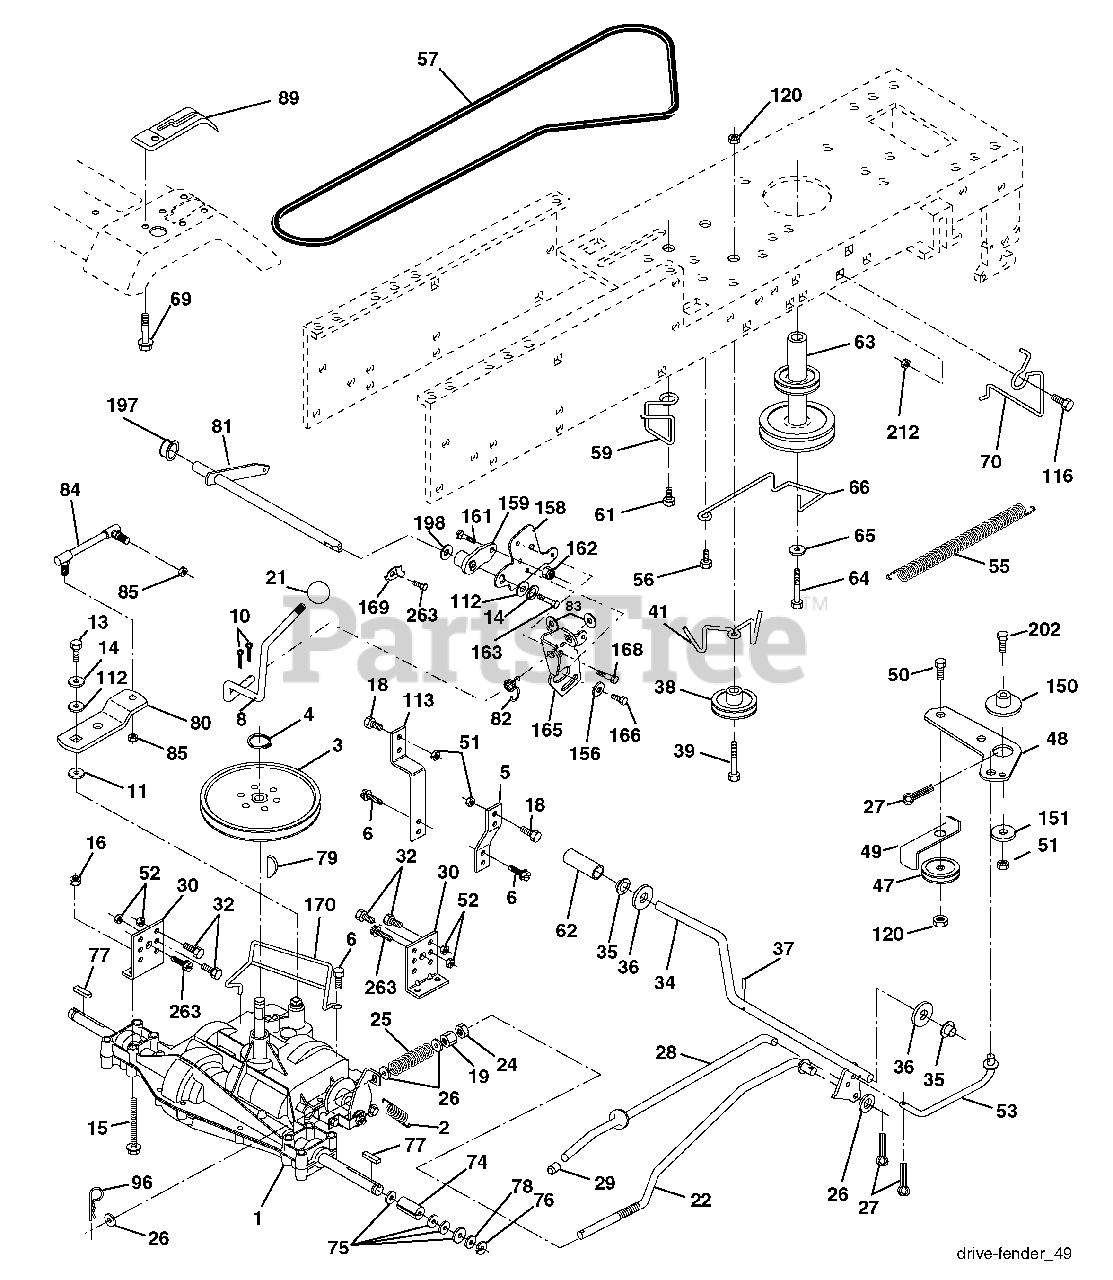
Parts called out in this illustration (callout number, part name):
2	Spring Return Brake
3	Pulley Transaxle 18"tires
4	Ring Retainer # 5100-62
5	Strap Torque 30 Degrees RH
6	Screw 5/16-18 x 3/4
8	Rod Shifter Blk
10	Pin Cotter 1/8 x 1 Cad
11	Washer Plate Shf 388 Sq Hole
13	Bolt 1/4-28 unf Gr. 8 w/Patch
14	Washer Lock Hvy Helical 1/4
15	Bolt Hex Flghd 5/16-18 Gr. 5
16	Nut 5/16-18
18	Bolt Fin Hex 3/8-16 unc x 1 Gr. 5
19	Nut lock Hex w/Ins 3/8-16 Unc
21	Knob Rd 1/2-13 Plstc Thds Blk
22	Rod Brake LT
24	Nut Hex Jam 3/8-16 unc
25	Spring Rod Brake 2 00 Zinc
26	Washer 13/32 x 13/16 x 16 Ga.
27	Pin Cotter 1/8 x 3/4 Cad
28	Rod Brake Parking LT/YT
29	Cap Brake Parking Black
30	Bracket Transmission
32	Bolt Fin Hex 5/16-18 x 3/4
34	Shaft Asm Pedal Foot Nibbed
35	Bearing Nylon Blk 629 Id
36	Washer 21/32 x 1 x 16 Ga.
37	Pin Roll 3/16 x 1"
38	Pulley Composite Flat
39	Bolt 3/8-16 x 2-3/4
41	Keeper Belt Idler
47	Pulley Idler V Groove Plastic
48	Bellcrank Clutch Grnd Drv STL
49	Retainer Belt Style Spring
50	Bolt Carr Sh 3/8-16 x 1-1/2 Gr. 5
51	Nut Crownlock 3/8-16 unc
52	Nut Crownlock 5/16-18 unc
53	Link Clutch 7 66
55	Spring Return Clutch 6 75
56	Screw 3/8-16 x 1-1/4
57	V-Belt Ground Drive 95
59	Keeper Belt Chassis Span Ctr
61	Screw 3/8-16 x .875
62	Cover Pedal Blk Round
63	Engine Pulley LT/YT
64	Bolt Hex 7/16-20 x 4 Gr. 5
65	Washer Lock Hvy Hlcl Spr 7/16
66	Keeper Belt Engine
69	Screw 1/4 x 1/2 unc
70	Guide Belt Mower Drive RH
74	Spacer Axle
75	Washer 25/32 x 1 1/4 x 16 Ga.
76	E-ring #5133-75
77	Key Square 2 0 x 1845/ 1865
78	Washer 25/32 x 1-5/8 x 16 Ga.
79	Key Woodruff
80	Arm Shift Transaxle
81	Shaft Asm Cross Taper
82	Spring Torsion Shift
83	Washer 17/32 x 3/4 x 16 Ga.
84	Link Transaxle
85	Nut Lock Center 1/4-28
89	Console Shift
96	Retainer Spring 1"
112	Washer 9/32 x 3/4 x 10 Ga.
113	Strap Torque 90 Degrees LH
116	Bolt Rdhd Sq Neck 3/8-16 x 1
120	Nut Lock Flg 3/8-16
150	Spacer Retainer Lt
151	Washer 13/32 x 2 x 10 Ga.
156	Washer Srrrtd 5/16 ID x 1.0 x .125
158	Bracket Shift Mount
159	Hub Shift
161	Bolt 1/4-20 x 3/4 Gr. 5
162	Nut Crownlock 1/4-20 unc
163	Bolt Hex Fin 1/4-20 unc x 1 Gr. 5
165	Bracket Pivot Lever
166	Screw 5/16-18 x 5/8
168	Bolt Shoulder 5/16-18 x .561
169	Plate Fastening
170	Keeper, Belt Transaxle
197	Nyliner Snap-In 5/8
198	Washer Nylon
202	Bolt Carr Sh 3/8-16 x 1-3/4 Gr. 5
212	Nut Hex Flg Lock
263	Screw 3/8-16 x 3/4
